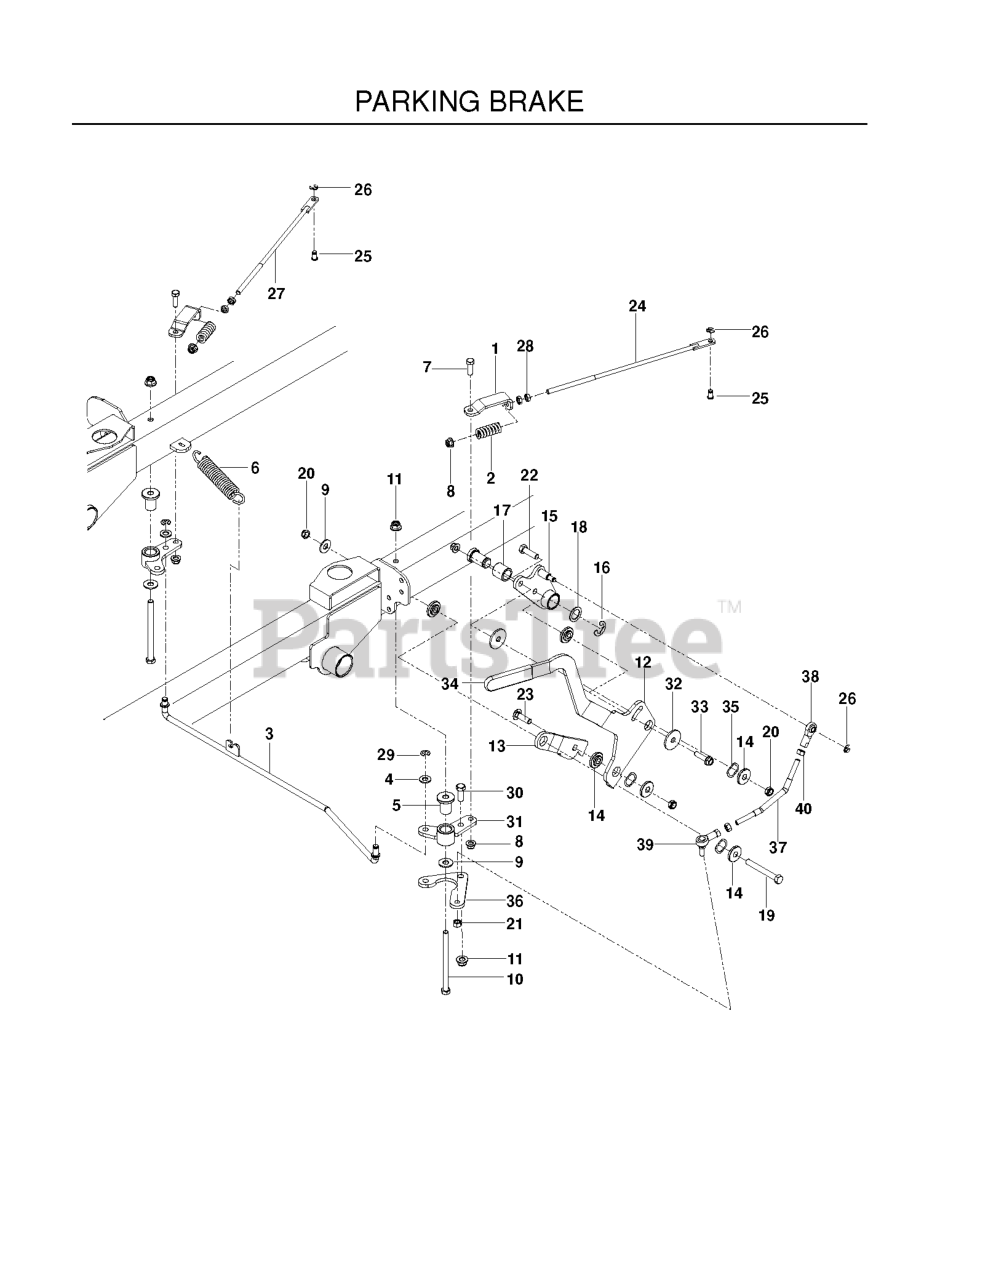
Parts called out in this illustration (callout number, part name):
1	BRACKET, BRAKE
3	LINKAGE, BRAKE, PRIMARY
4	WASHER 3/8 SAE FLAT
5	BUSHING, PIVOT
7	HCS 5/16C X 1
8	5/16-18 NYLOC FLANGE NUT
9	WASHER 3/8 FLAT
10	SCREW, 3/8C X 5 HEX CAP
11	NUT 3/8-16 HEX FLG NYLOC ZD
12	LEVER.BRAKE.BLACK
13	LINK, FOLLOWER
14	BUSHING, BRAKE
15	WELDMENT, ARM, BRAKE
16	E RING 3/4
17	BUSHING, SLEEVE 3/4 X 1.0
18	WASHER .787 X 1.125 X .06
19	HCS 3/8C X 3
20	NUT HEX 3/8-16 NYLON, THIN
21	NUT 5/16F NYLOC
22	HCS 3/8C X 1 1/4 GR5
23	RHSNB 3/8-16 X 1-1/4
24	LINKAGE, BRAKE RR
25	PIN, BRAKE ARM
26	RING RETAINING EXT 5/16
27	LINKAGE, BRAKE, RT-RR
28	NUT 5/16-18 HEX JAM ZD
29	E RING 3/8"
30	HCS 3/8-16X1.GRD.5.ZD
31	BELLCRANK, BRAKE, WLDMT
32	WASHER, FRICTION, 1/8
33	HHFS 5/16-18 X 1.25 TPBLT GD 5
35	WASHER, .825 X 1.087, WAVE
36	PLATE, BRAKE, BLK
37	LINKAGE, BRAKE
38	BALL JOINT, RIGHT HANDED
39	SPHERICAL ROD END, RH
